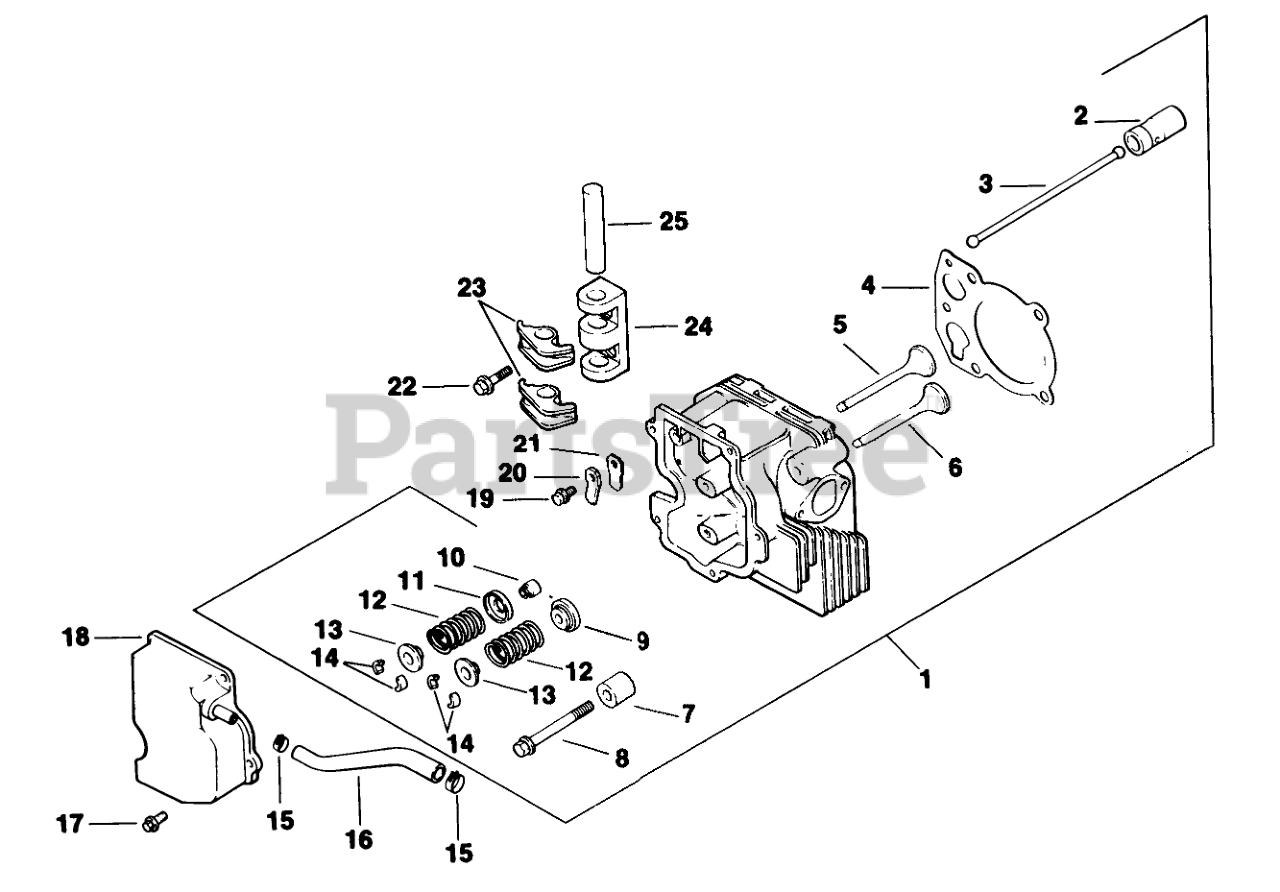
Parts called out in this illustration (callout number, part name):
1	Kit Cylinder Head
2	Lifter-Valve
3	Rod-Push
4	Gasket-Cylinder Head
5	Valve-Intake STD
6	Valve-Exhaust STD
7	Spacer-Head Bolt
8	Screw-Cylinder Head
10	Seal
11	Retainer-Spring
12	Pulley
13	Cap-Valve Spring
14	Kit-Retainer
15	Clamp
16	Hose-Breather
17	Screw
18	Cover-Valve
20	Retainer-Reed
22	Screw
23	Arm-Rocker
24	Bridge-Rocker Arm
25	Shaft-Rocker Arm
1208915	Spring-Valve, Exhaust
